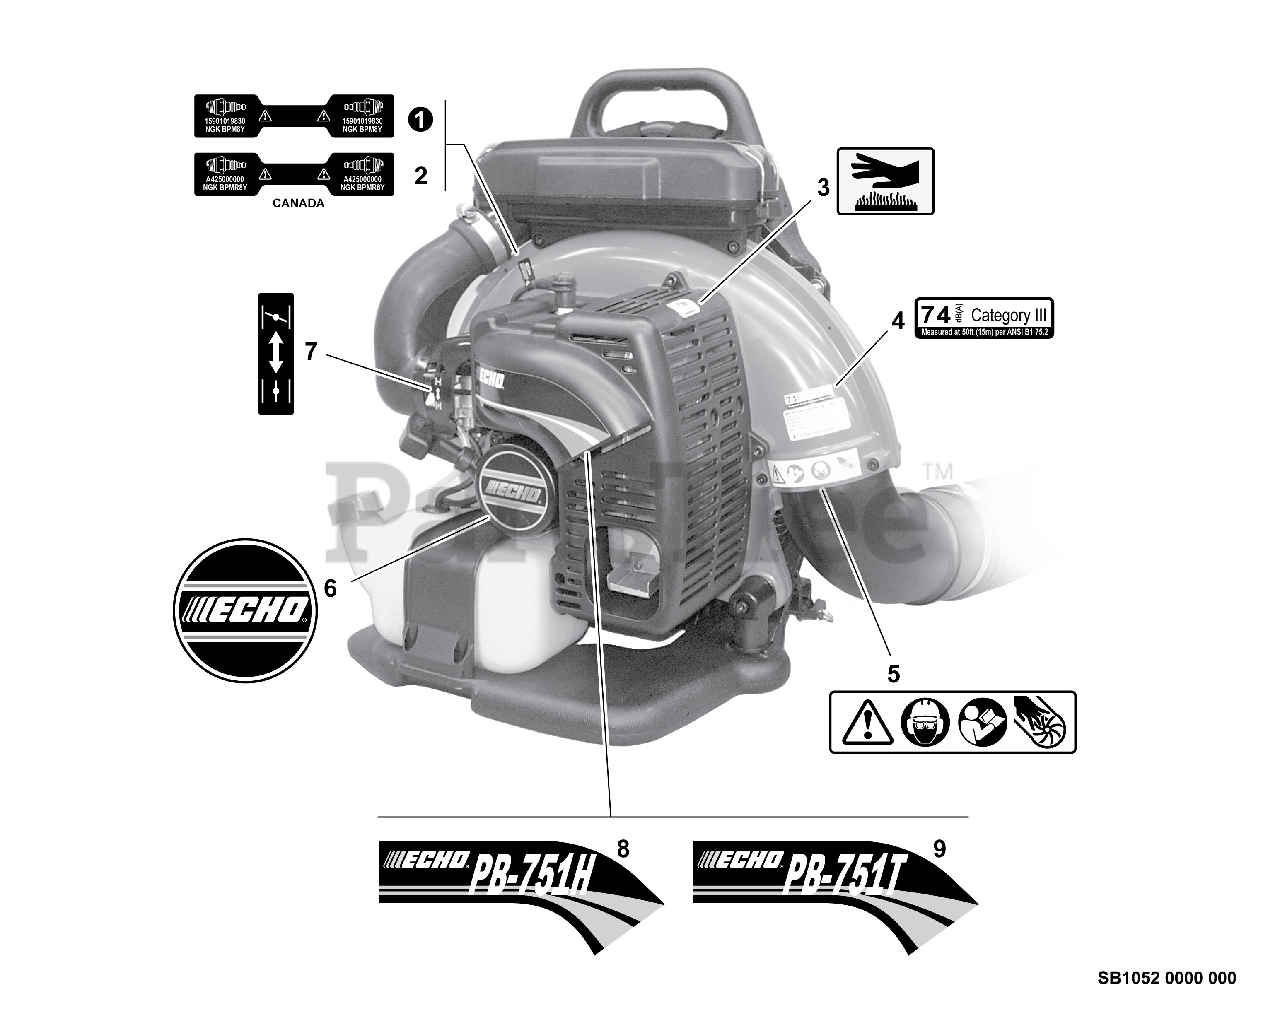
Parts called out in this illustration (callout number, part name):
1	LABEL - SPARK PLUG -- BPM-8Y
2	LABEL - SPARK PLUG -- BPMR-8Y
3	LABEL - HOT SURFACE
4	LABEL - NOISE 74dB(A) CAT III
5	LABEL - CAUTION
6	LABEL - ECHO
7	LABEL - CHOKE
8	LABEL - MODEL PB-751H
9	LABEL - MODEL PB-751T
